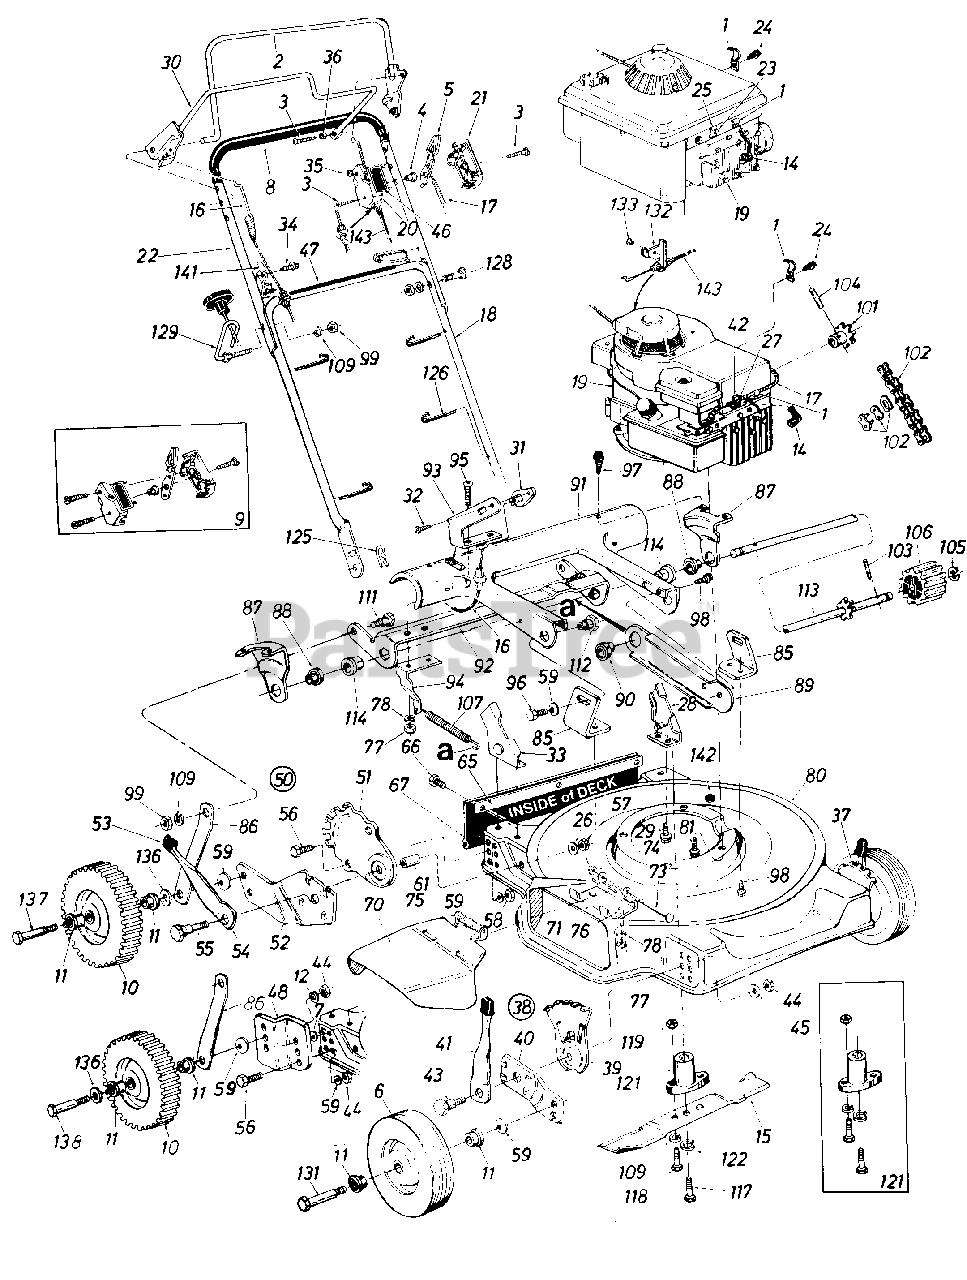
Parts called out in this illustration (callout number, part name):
1	Casing Clamp
2	Control Handle Ass'y.-L.H.
3	Truss Mach. Hi-B Tap Scr. #12 x 1.5"
4	Control Disc Pin
5	Throttle Control Lever
6	Front Wheel Ass'y. Comp.
8	Grip
9	Control Housing Comp.
10	Rear Wheel Ass'y. Comp.
11	Fl. Ball Brg 2 I.D.
12	L-Wash 3/8 I.D.
14	Spark Plug Insulator
15	22" Blade
16	Clutch Cable w/Spring-32"
17	Throttle Wire-53"
18	Lower Handle
19	Engine
20	Clutch Panel Half
21	Control Panel Half
22	Upper Handle
23	Hex AB-Tap Scr. #8 x .50"
24	Hex B-Tap Scr. #10 x .38"
25	Casing Clamp
26	Bell-Wash. 5/16" I.D.
27	Hex "B"-Tap Scr. #10 x .38"
28	Handle Brkt. Ass'y-L.H.
29	Hex B-Tap Scr. 5/16-18 x .5"
30	S.P. Bail Ass'y.
31	Barrel Cable Hold-Down R.H.
32	B-Tap Scr. #10 x .38 Lg.
33	Handle Brkt. Ass'y-R.H.
34	Hex Wash. AB-Tap Scr. 5/16 x .75"
35	Spr-Wash. .206 I.D. x .448
36	Spacer .23 I.D. x .30 O.D.
37	Front Height Adj. Ass'y.-L.H.
38	Front Height Adj. Ass'y.-R.H.
39	Height Adj. Plate
40	Pivot Bar
41	Spring Lever Ass'y. w/Knob
42	Casing Clamp
43	Shld. Bolt .50 Dia. x .430
44	Hex Nut 3/8-16 Thd.
45	Bell-Wash. .39 I.D. x 1.38 0. D .
46	Control Label
47	Instruction Label
48	Wheel Brkt.
50	Rear Height Adj. Ass'y.-R.H.
51	Index Plate
52	Pivot Bar-R.H.
53	Spring Lever Knob
54	Spring Lever
55	Shld. Bolt .50 Dia. x .433
56	Hex Bolt 3/8-16 x .75
57	Hex Cent. L-Nut 5/16-18 Thd.
58	Hex Nut 3/8-16 Thd.
59	Bell-Wash. .40 I.D. x .88 O.D.
61	Spacer .383 I.D. x .503 O.D.
65	Retaining Strip
66	Hex AB-Tap Scr. 1/4 x .62
67	Rear Flap Ass'y.
70	Chute Deflector Ass'y.
71	Adapter Plate
73	Pivot Pin
74	Push Nut 1/4"
75	Torsion Spring
76	Hex Bolt 1/4-20 x .50 Lg.*
77	Hex Nut 1/4-20 Thd.
78	L-Wash. 1/4 I.D.*
80	22" Deck Ass'y
81	Hex TT-Tap Scr. 3/8-16 x 1.0
85	Pivot Brkt.
86	Link 4.58
87	Axle Brkt.
88	Fl. Ball Brg. 1/2" I.D.
89	Brg. Support
90	Fl. Ball Brg. 1/2" I.D.
91	Pinion-Pivot Cover
92	Drive Engagement Cam
93	Engagement Arm-L.H.
94	Spring Bracket
95	Carriage Bolt '/4-20 x .62
96	Hex Bolt 3/8-16 x .50 Lg.
97	Hex AB-Tap Scr. 1/4 x .62
98	Hex AB-Tap '/4 x .62"
99	Hex Nut 5/16-18 Thd.
101	10T Sprocket Ass'y.
102	#48 Chain 1/2" Pitch 50 Links
103	Spring Pin Spir. 3/16 Dia. x 1 .25
104	Spring Pin Spir. 3/16 Dia. x 1 .0
105	E-Ring For .500 Dia. Shaft
106	Drive Pinion
107	Extension Spring 4.25 Lg.
109	L-Wash. 5/16 I.D.
111	Shld. Bolt .437 Dia. x .162
112	Shld. Nut .625 Dia. x .165
113	Pinion Shaft w/7T Sprocket
114	Fl. Ball Brg. .501 I.D.
117	Hex Bolt 3/8-24 x 2.25
118	Hex Bolt 5/16-24 x 1.0-Spec.
119	Hex Nut 5/16-24 Thd.
121	Blade Adapter Kit
122	L-Wash. 3/8 I.D.-H.D.
125	Intern. Cot. Pin 5/16 Dia.
126	Cable Tie
128	Curved Carriage Bolt 5/16-18 x 1.38" Lg.
129	Rope Guide Bolt
131	Front Axle Bolt
132	Cable Bracket
133	Pop Rivet .156" Dia. x .379
136	Fl-Wash. .531 I.D. x .93 O.D.
137	Rear Axle Bolt
138	Rear Axle Bolt
141	Cable Brkt.
142	Plastic Plug
143	Control Cable-39" (Green)
